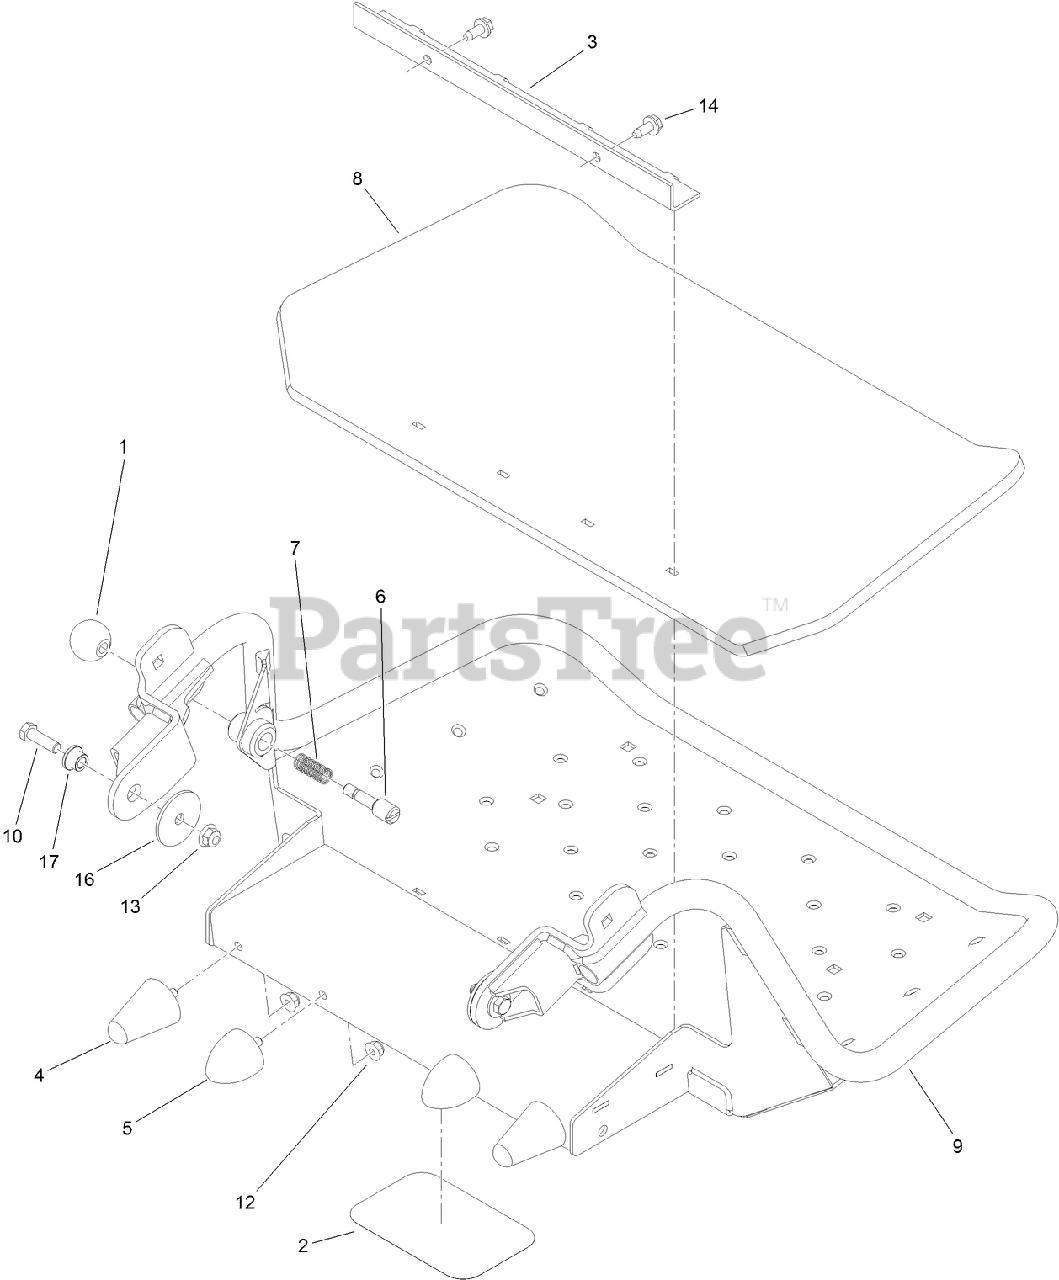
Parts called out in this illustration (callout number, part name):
1	KNOB-BALL
2	DECAL
3	CLAMP-SHIELD
4	BUMPER-RUBBER
5	BUMPER-RUBBER
6	PIN-LATCH
7	SPRING
8	MAT-FOOT
9	PLATFORM
10	SCREW-HH
12	NUT-HF, NI
13	NUT-HF, NI
14	SCREW-HWHTF
16	WASHER-FLAT
17	BUSHING-FLANGED
